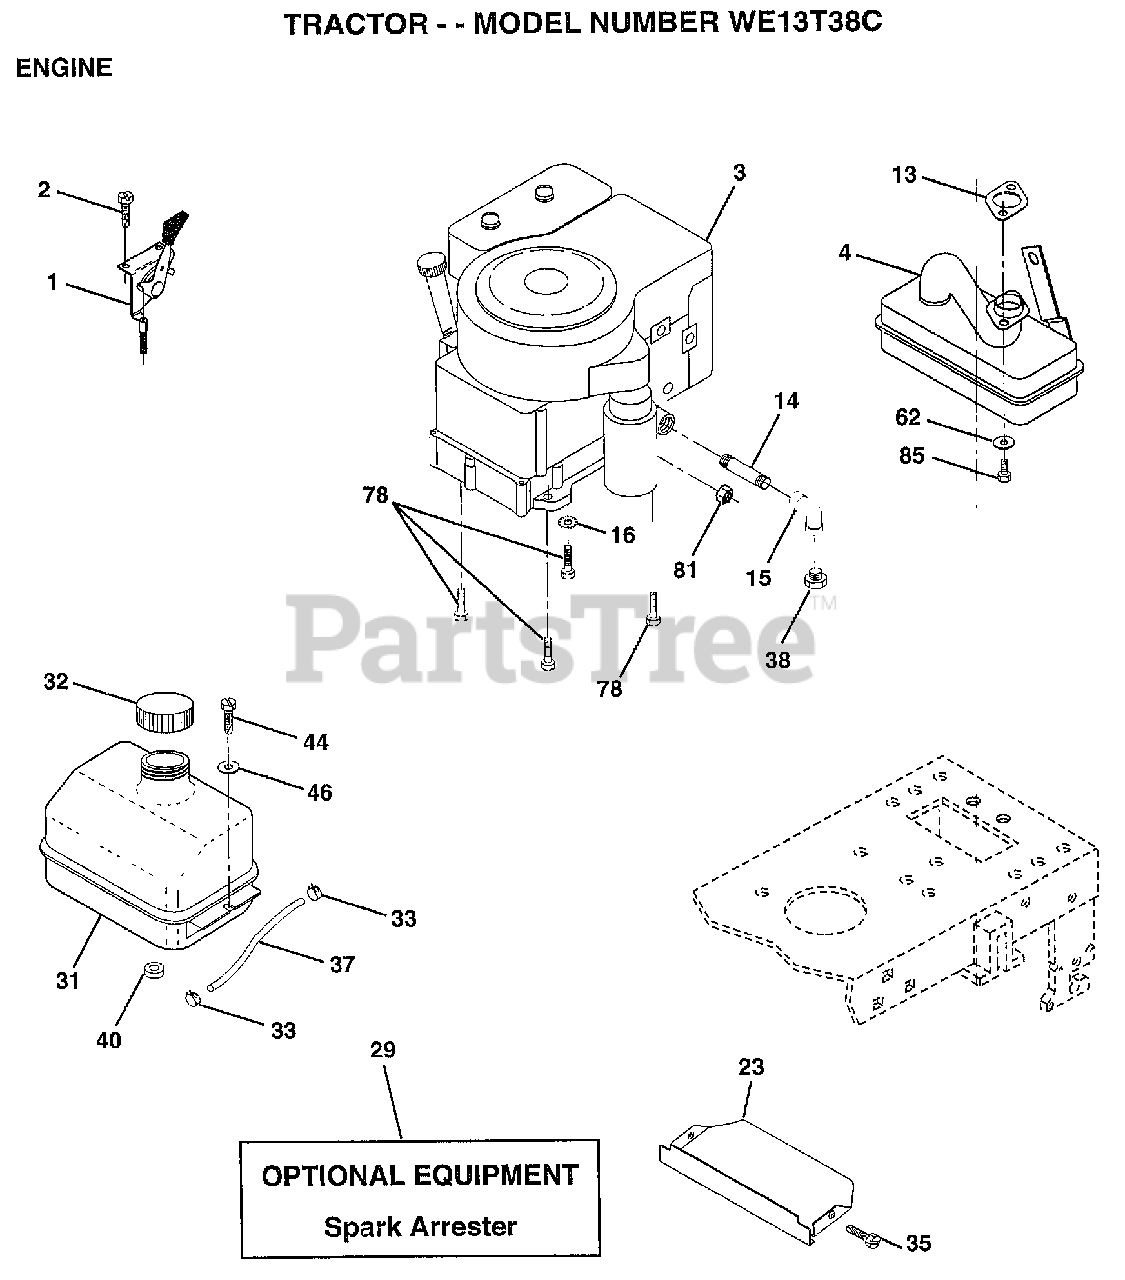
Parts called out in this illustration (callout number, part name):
1	CONTROL-THROT/CHO
2	SCREW LT
4	MUFFLER TEC. 13HP
14	PIPE NIPPLE LT
15	ELBOW
16	LOCKWASHER
23	SHIELD.BRN/DBR.GD
31	TANK.FUEL.LT.
32	CAP ASM FUEL
33	HOSE CLAMP
35	SCREW
37	LINE FUEL
44	SCREW HEX CRT
46	WASHER
62	LOCKWASHER
78	SCREW
81	NUT
85	SCREW HEX HD CAP
